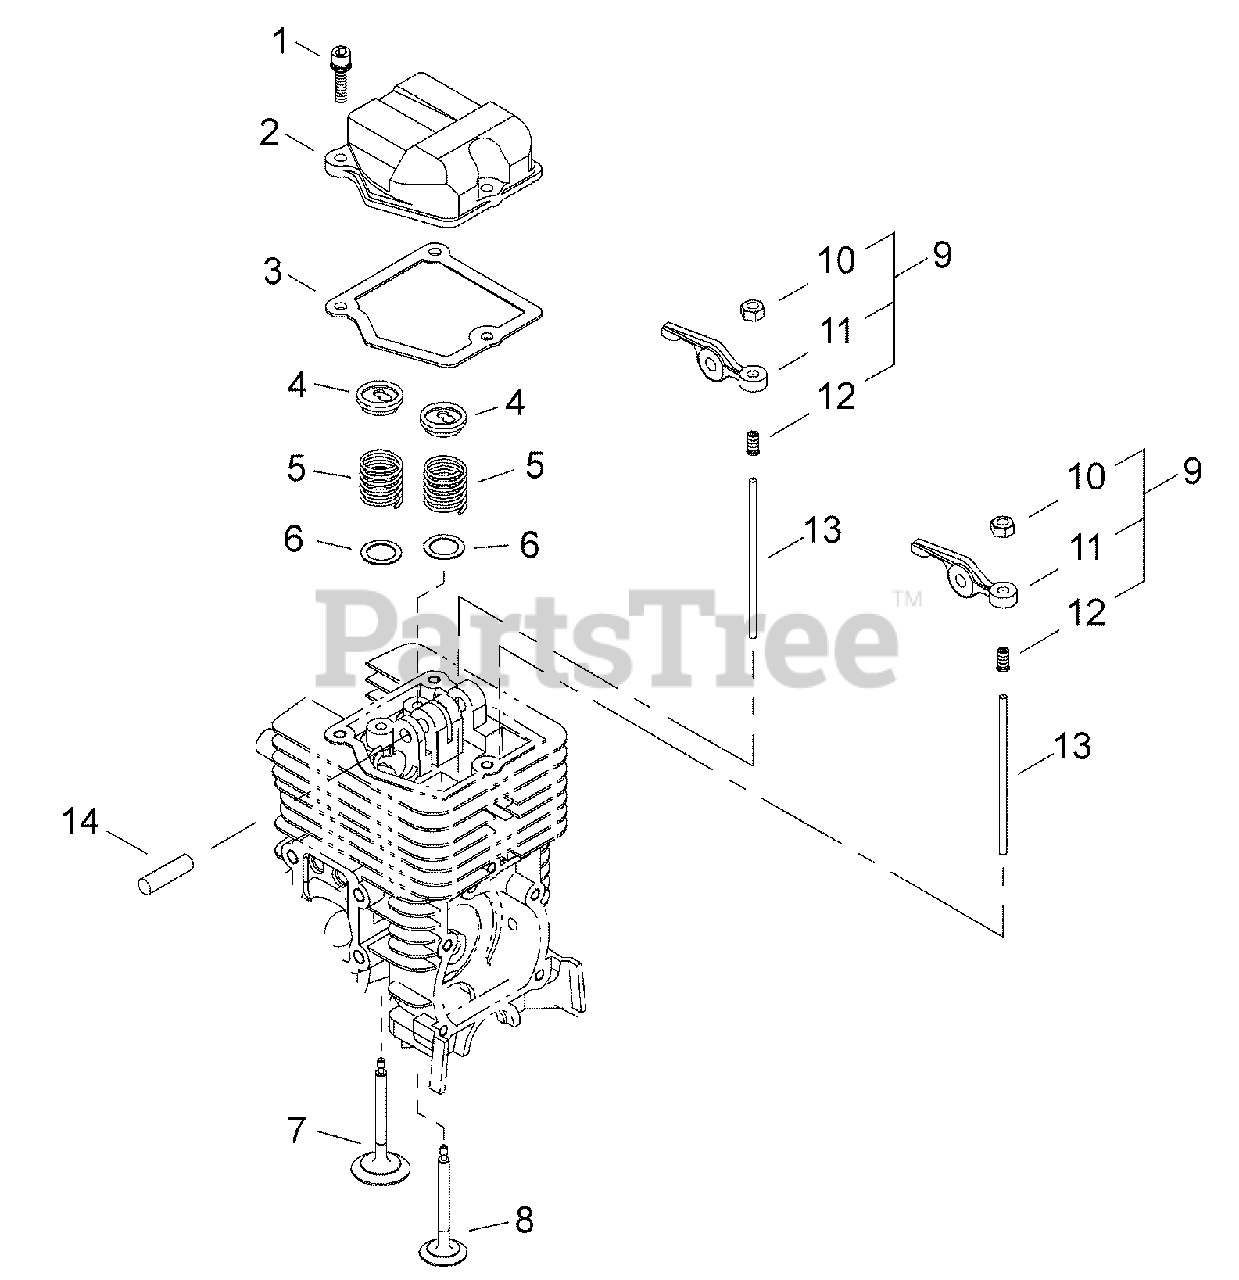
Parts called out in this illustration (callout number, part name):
1	BOLT M4×12
2	COVER, ROCKER ARM
3	GASKET, ROCKER ARM
4	RETAINER, VALVE
5	SPRING, VALVE
6	WASHER, VALVE 9
7	VALVE, INTAKE
8	VALVE, EXHAUST
9	ARM ASSY, ROCKER
10	NUT, ADJUSTER LOCK 5
11	ARM, ROCKER
12	SCREW, ADJUSTER
13	PUSHROD
14	SHAFT, ROCKER ARM Ø5×31.8 MM
